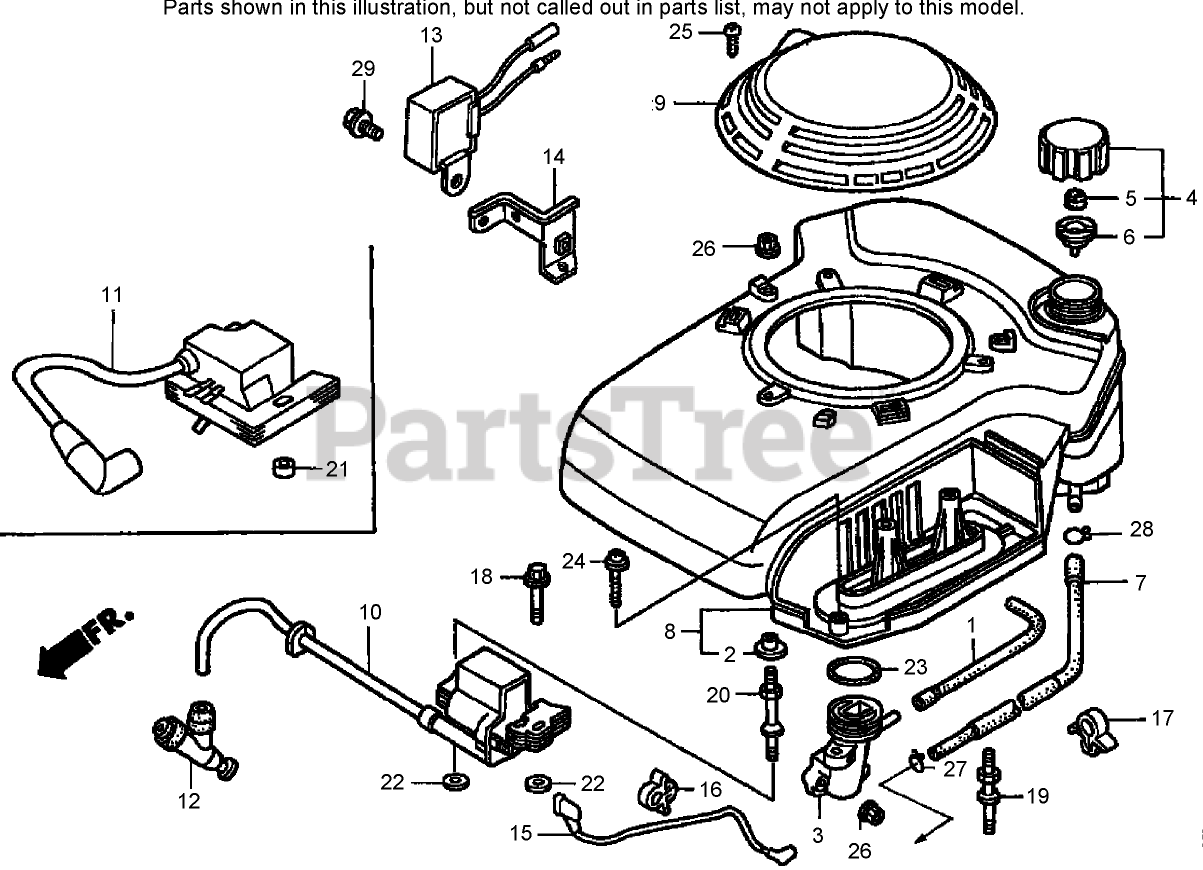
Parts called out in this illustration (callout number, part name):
1	Tube-Breather
2	COLLAR-CLEANER, AIR
3	ELBOW-CLEANER, AIR
4	FUEL TANK CAP ASM
5	Sponge-BREATHER, Fuel Cap
6	GASKET-CAP, FUEL
7	FUEL TANK TUBE ASM
8	COVER-FAN
9	HOOD-COVER, FAN
9	HOOD-FAN COVER
10	IGNITION COIL ASM
12	NOISE SUPPRESSOR CAP ASM
15	WIRE-SWITCH, STOP
16	HOLDER-WIRE, STOP SWITCH
17	CLAMP-PIPE, BRAKE
18	BOLT-FLANGE (6X28) (C T200) (engine serial numbers starting at 6901761)
19	BOLT A-STUD
20	BOLT-STUD
22	WASHER-PLAIN (6MM)
23	O-Ring (33.3X3.5)
24	SCREW-WASHER (6X35)
25	Screw-Tapping (4X20)
26	NUT-FLANGE (6 mm)
27	CLIP-TUBE (B8)
28	CLIP-TUBE (B10)
28	CLIP-TUBE (C9)
